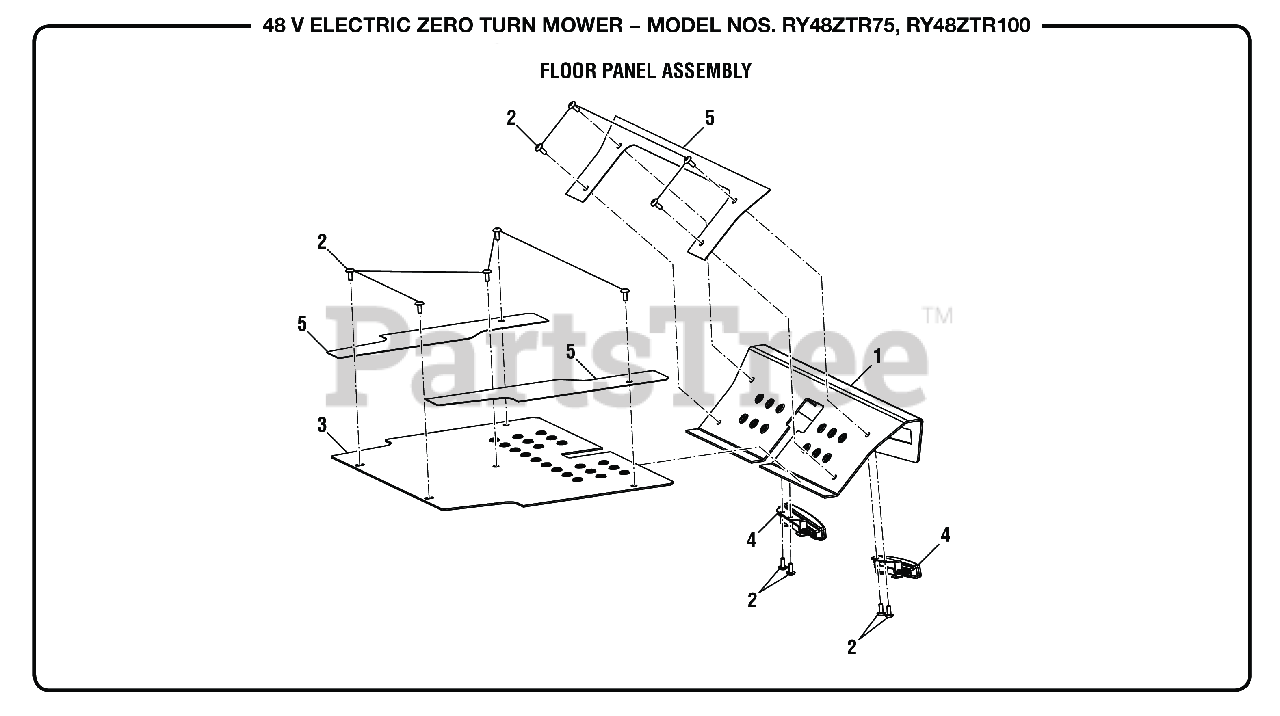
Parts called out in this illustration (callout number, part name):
1	Foot Rest Plate
2	Screw (M6 x 10 mm, Soc. Button Hd.)
3	Floor Plate
4	Light Assembly
5	Anti Slip Decal Package
